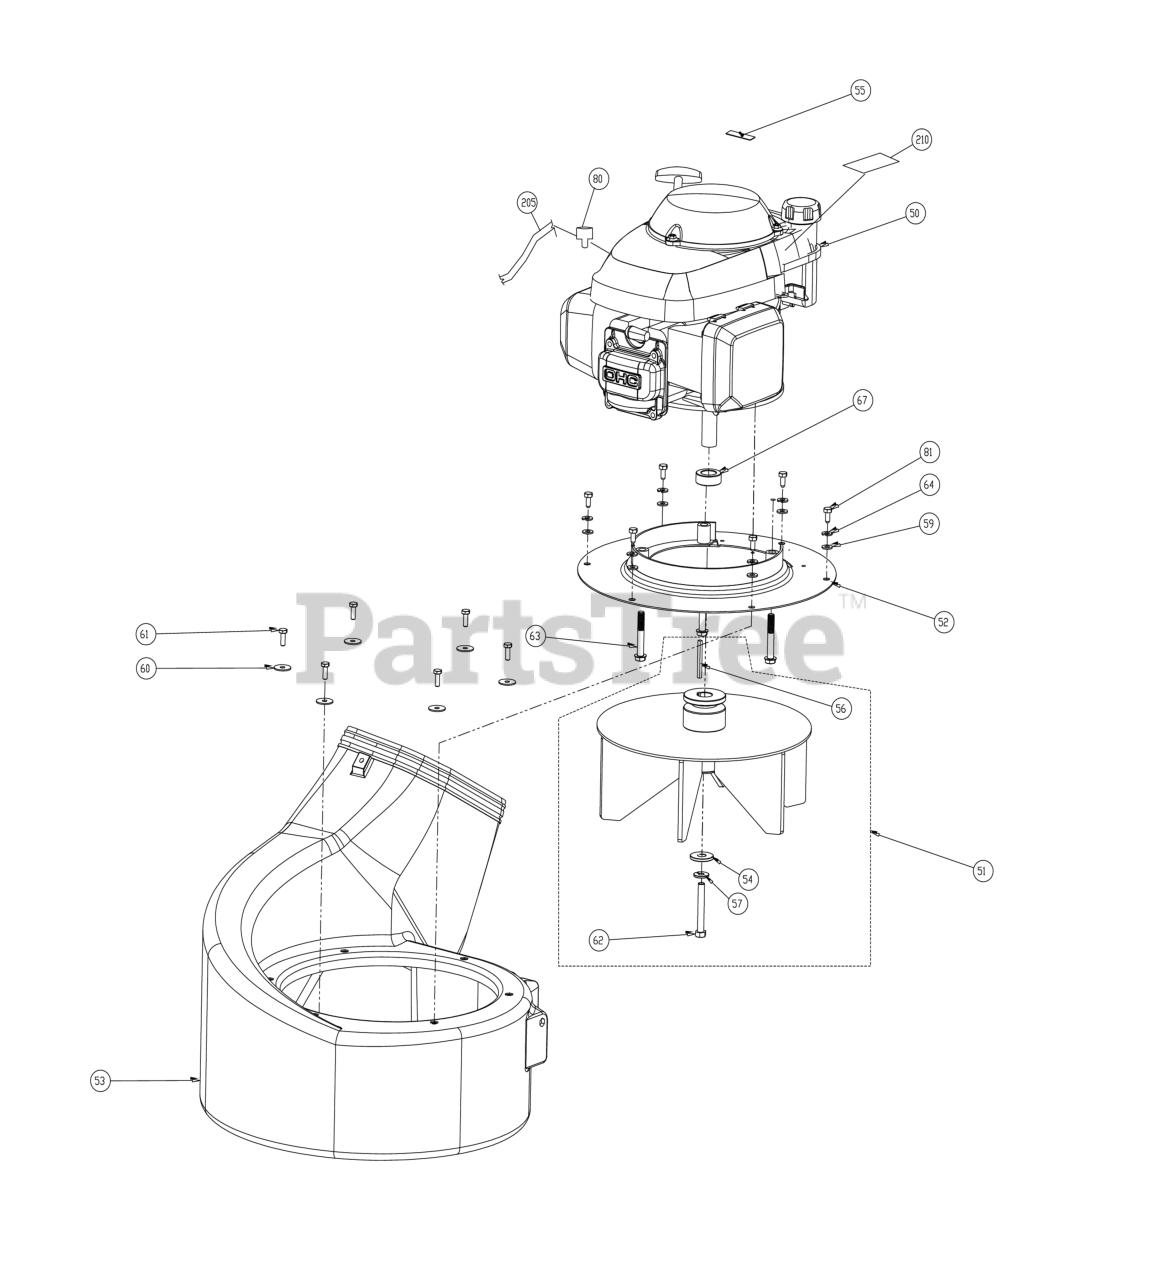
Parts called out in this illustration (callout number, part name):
50	ENGINE HONDA 6.5 VERTICAL GSV190
51	IMPELLER ASSEMBLY SP MV VAC
52	PLATE TOP WA SP VAC
53	HOUSING WITH PVC LINER MV
54	WASHER 1.5 OD X .453 ID X .25 THK
56	KEY 3/16" SQ X 2 1/8"
57	WASHER LOCK 3/8" S/T MED
59	WASHER 1/4"SAE9/32"X5/8"X1/16"
60	WASHER FLAT FENDER 1/4"
61	SCREWCAP 1/4"-20X3/4" HCS ZP
62	SCREWCAP 3/8"-24 X 2 3/4"GR.8
63	SCREWCAP 3/8"-16X2 1/2" TAPTITE
64	WASHER LOCK 1/4" S/T MED
67	SPACER 1.50 OD X .890 ID X .50 THK
80	TERMINAL 18-14 BLUE T-TAP
81	SCREWCAP 1/4"-20 X 5/8" GR 5
